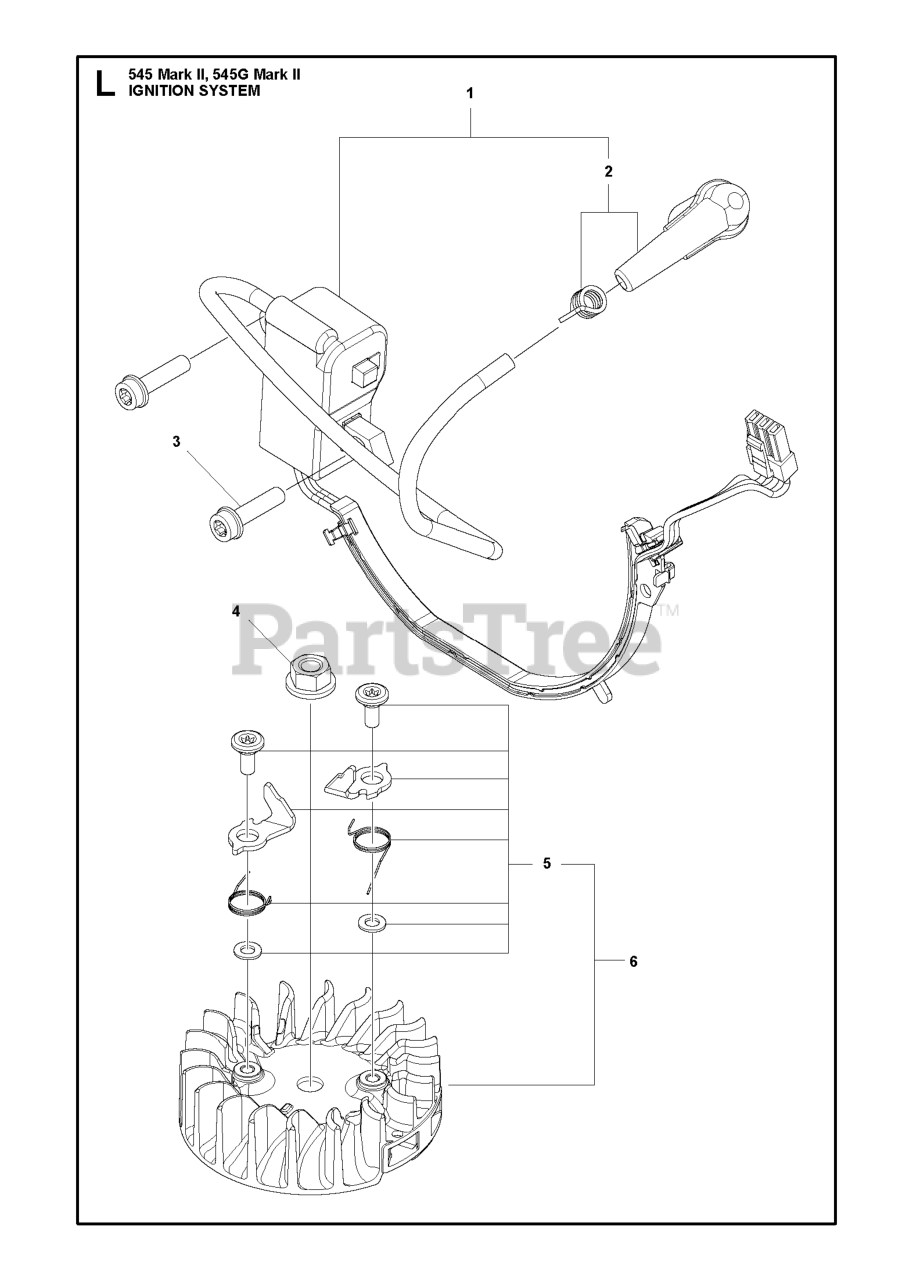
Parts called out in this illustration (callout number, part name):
1	IGNITION MODULE
2	CAP ASSY 50CC MARK II
4	NUT W/ WASHER
5	SCREW KIT PAWL H550/545 MARK I
6	FLYWHEEL ASSY
